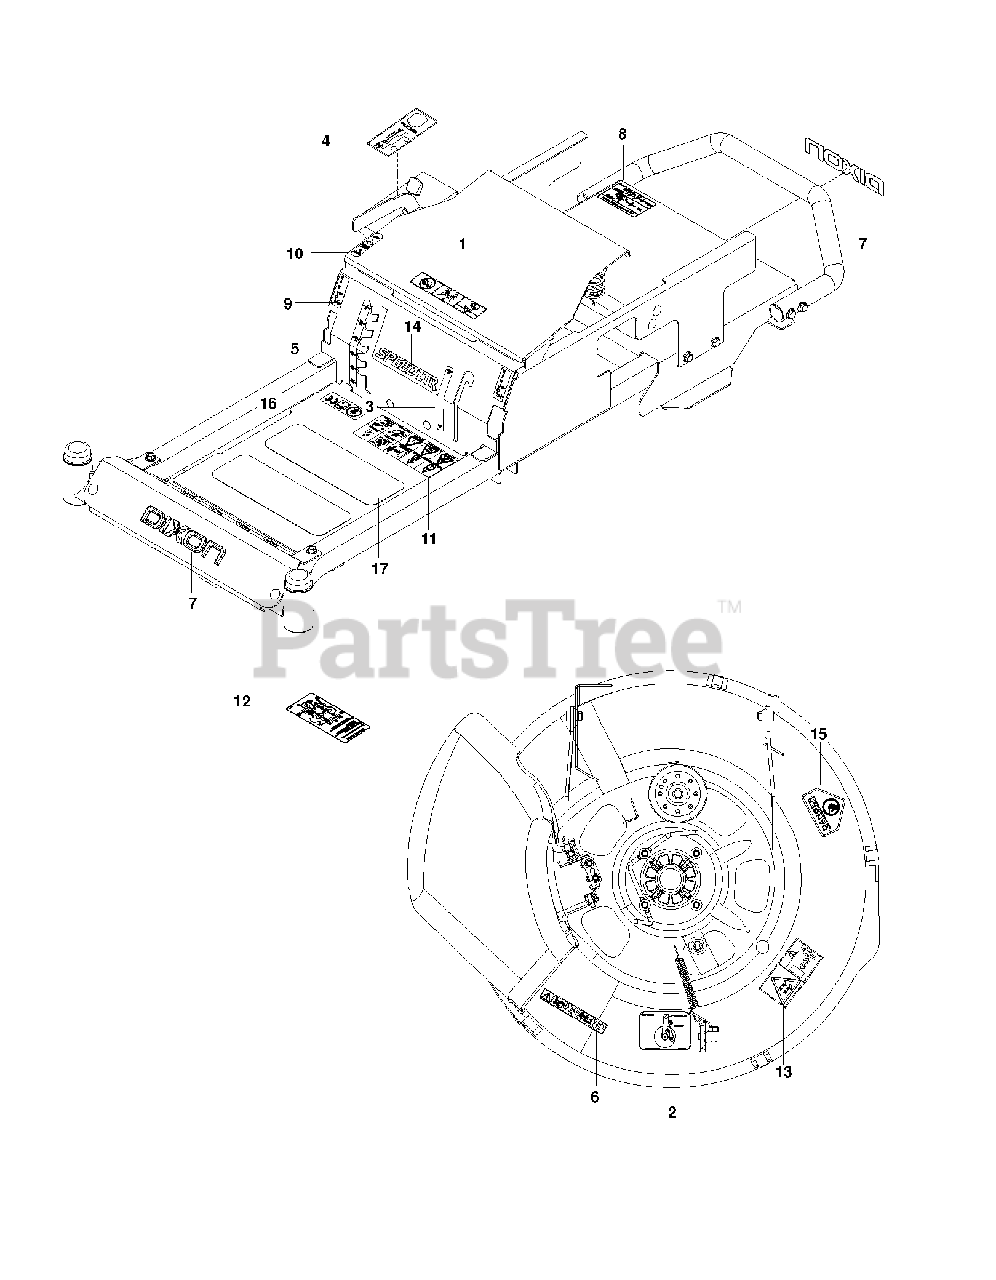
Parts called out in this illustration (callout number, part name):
2	DECAL, BELT ROUTING
3	DECAL, BLADE ENGAGEMENT
4	DECAL, CONTROL PANEL
5	DECAL, DECK HEIGHT
6	DECAL, DEFLECT WARNING
8	DECAL, DO NOT MOUNT
9	DECAL, MOTION CONTROL
10	DECAL, PARK BRAKE
11	DECAL, SAFETY WARNING
12	DECAL, SERVICE
13	DECAL, EURO SEVERING
14	DECAL, SPEEDZTR 6.5"
15	DECAL, CPSC
17	ANTI-SKID PAD
